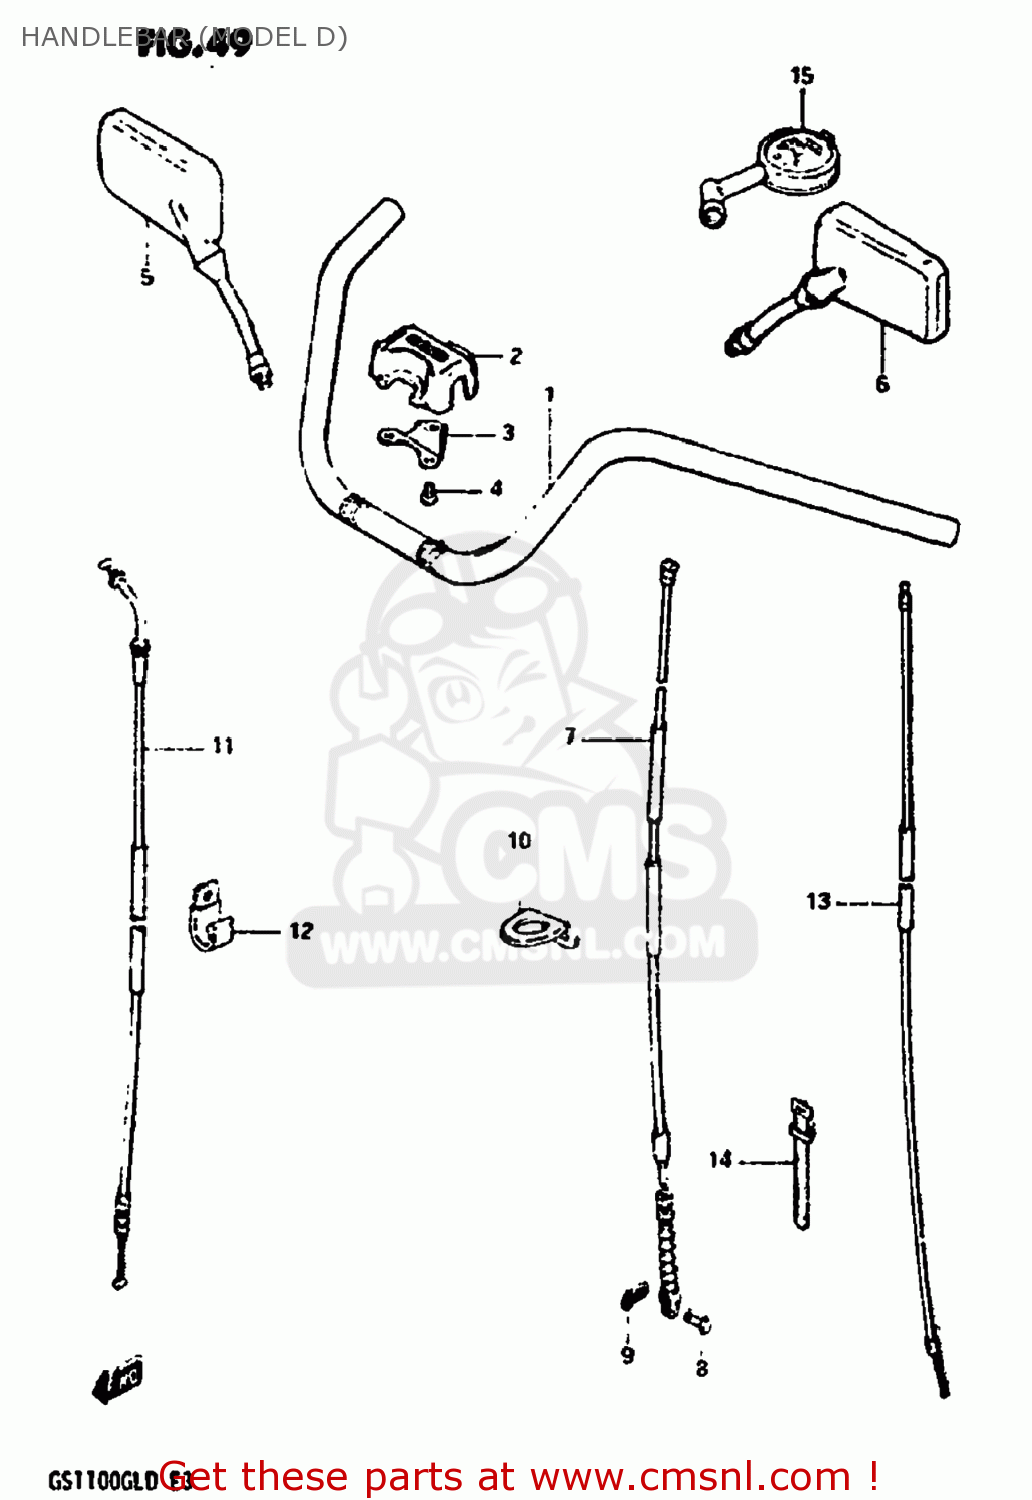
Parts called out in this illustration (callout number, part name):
1	HANDLEBAR
2	COVER,STEERING HEAD
3	BRACKET,STEERING HEAD
4	SCREW
5	MIRROR ASSEMBLY,REAR VIEW
6	MIRROR ASSEMBLY,REAR VIEW
7	CABLE ASSY,CLUTCH
8	PIN(L:15)
9	PIN
10	GUIDE,CLUTCH CABLE
11	CABLE ASSEMBLY,THROTTLE
12	CLAMP
13	CABLE ASSEMBLY,STARTER
14	CLAMP(L:80)
15	GAUGE ASSY,AIR PRESSURE
